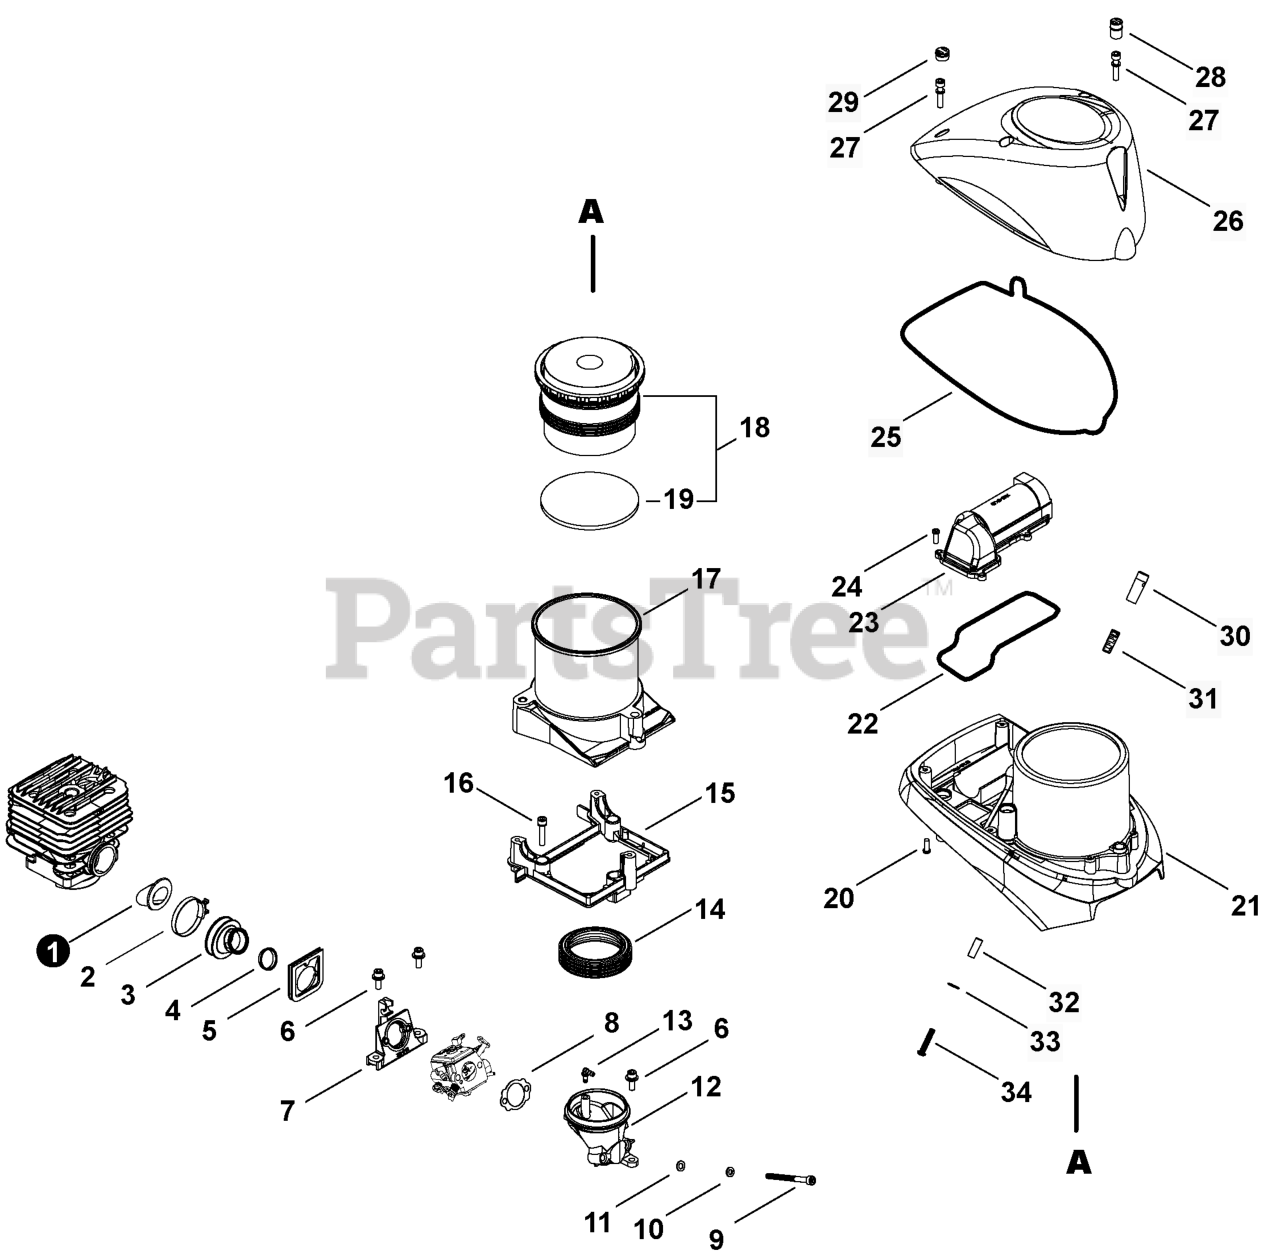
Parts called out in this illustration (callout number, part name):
1	PIPE, INTAKE
3	BELLOWS, INTAKE
4	SLEEVE 18
7	INSULATOR, INTAKE
8	GASKET, INTAKE
9	BOLT 5x60
10	WASHER, SPRING 5
11	WASHER, FLAT 5.5x10x0.8
12	ELBOW, CARBURETOR
13	CONNECTOR, PIPE
15	SUPPORT, FILTER
16	BOLT M5x25
17	CASE ASSY, AIR FILTER
18	FILTER KIT, AIR
19	FILTER, DISK
20	SCREW 4
21	COVER, AIR FILTER
22	SEAL, AIR FILTER
23	COVER, AIR FILTER
24	SCREW 4
25	SEAL, CLEANER
26	COVER, CYLINDER
28	GROMMET, PLUG
29	GROMMET, PLUG
30	SHAFT, DECOMPRESSSION
31	SPRING, COMPRESSION
33	WASHER 5.5x12x0.8
34	SCREW 5
